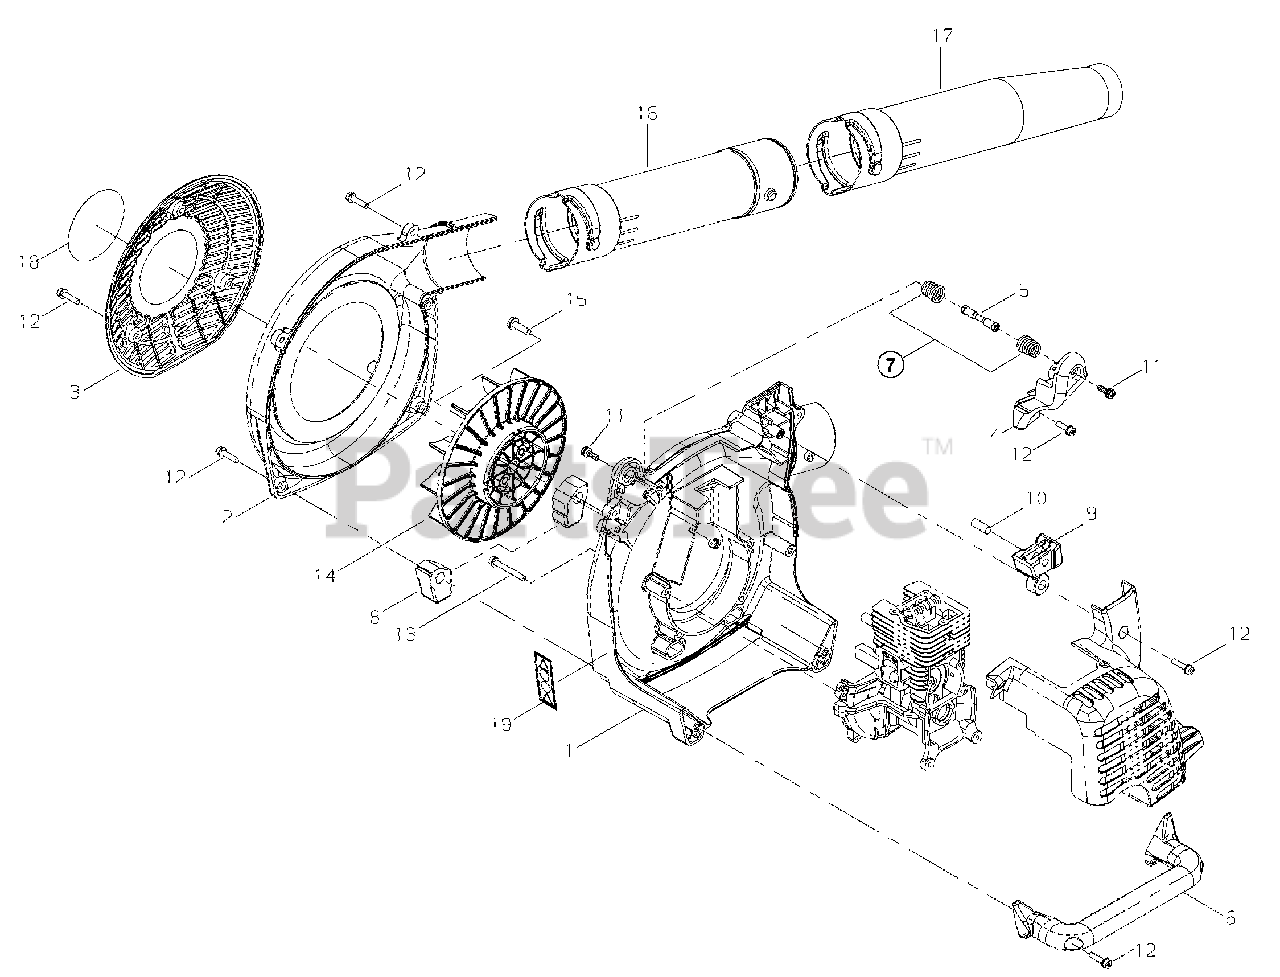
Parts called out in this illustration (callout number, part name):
1	COVER, FAN - RIGHT
2	COVER, FAN - LEFT
3	COVER, INTAKE
4	COVER, HANDLE
5	NUT
6	HANDLE - LOWER
7	SPRING
8	CUSHION - REAR
9	CUSHION
10	PIN
11	SCREW - 5X16
12	BOLT - 5X20
13	SCREW - 5X40
14	FAN
15	SCREW - 6X20
16	PIPE
17	NOZZLE
18	LABEL - MODEL EB2510
19	LABEL - CAUTION
